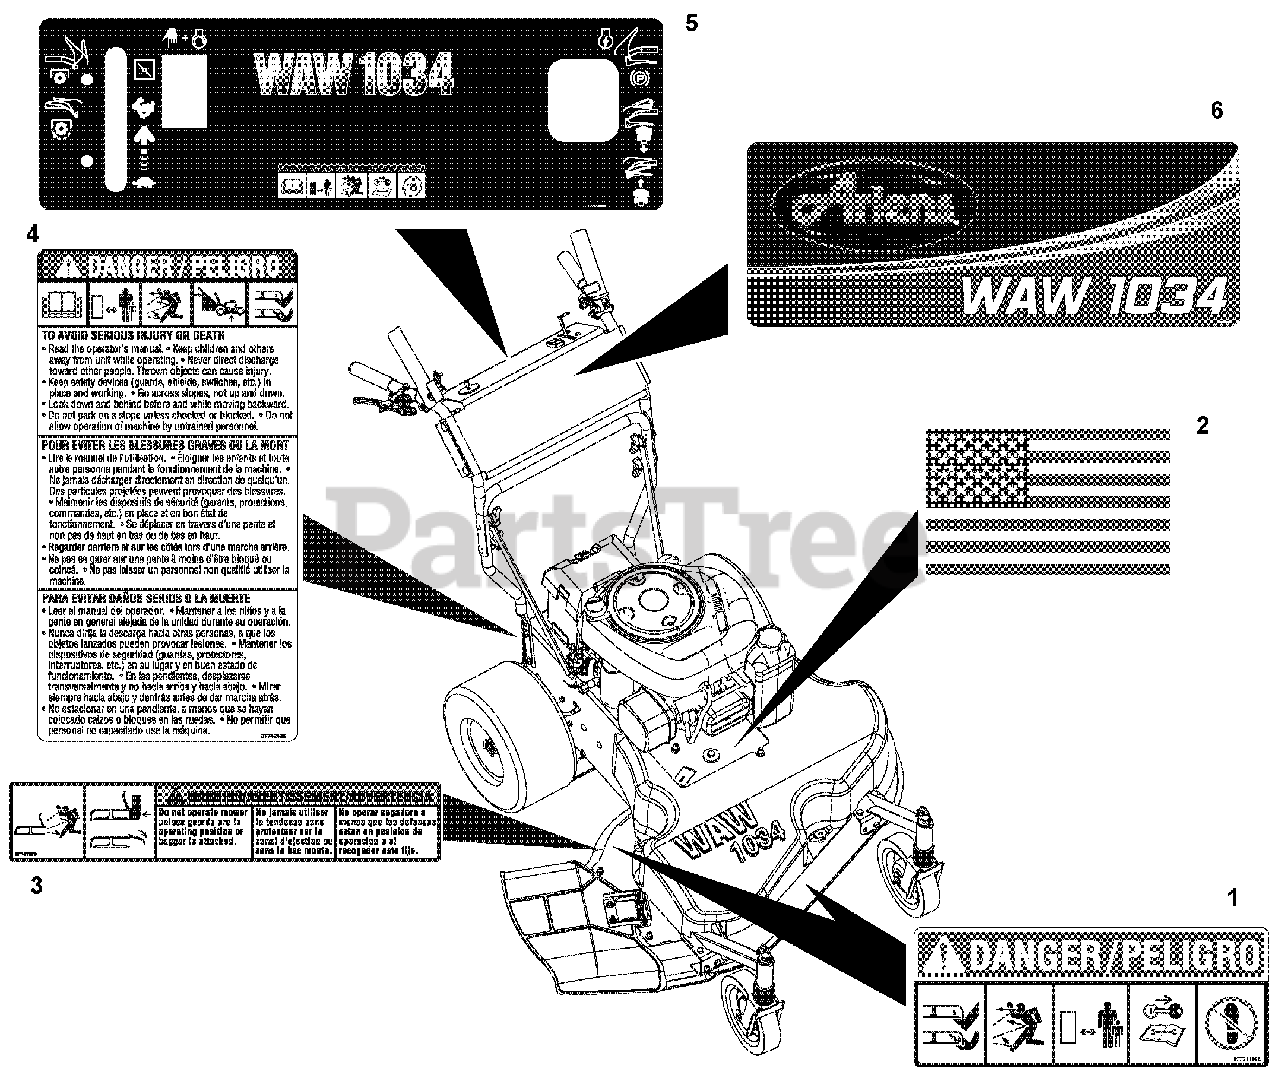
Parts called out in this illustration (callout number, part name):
1	DECAL, MOWER PAN DANGER
2	DECAL, AMERICAN FLAG
3	DECAL, WARNING
4	DECAL, BILINGUAL DANGER
5	DECAL, WAW OPERATIONAL
6	DECAL,WAW 34 ARIENS DASH
